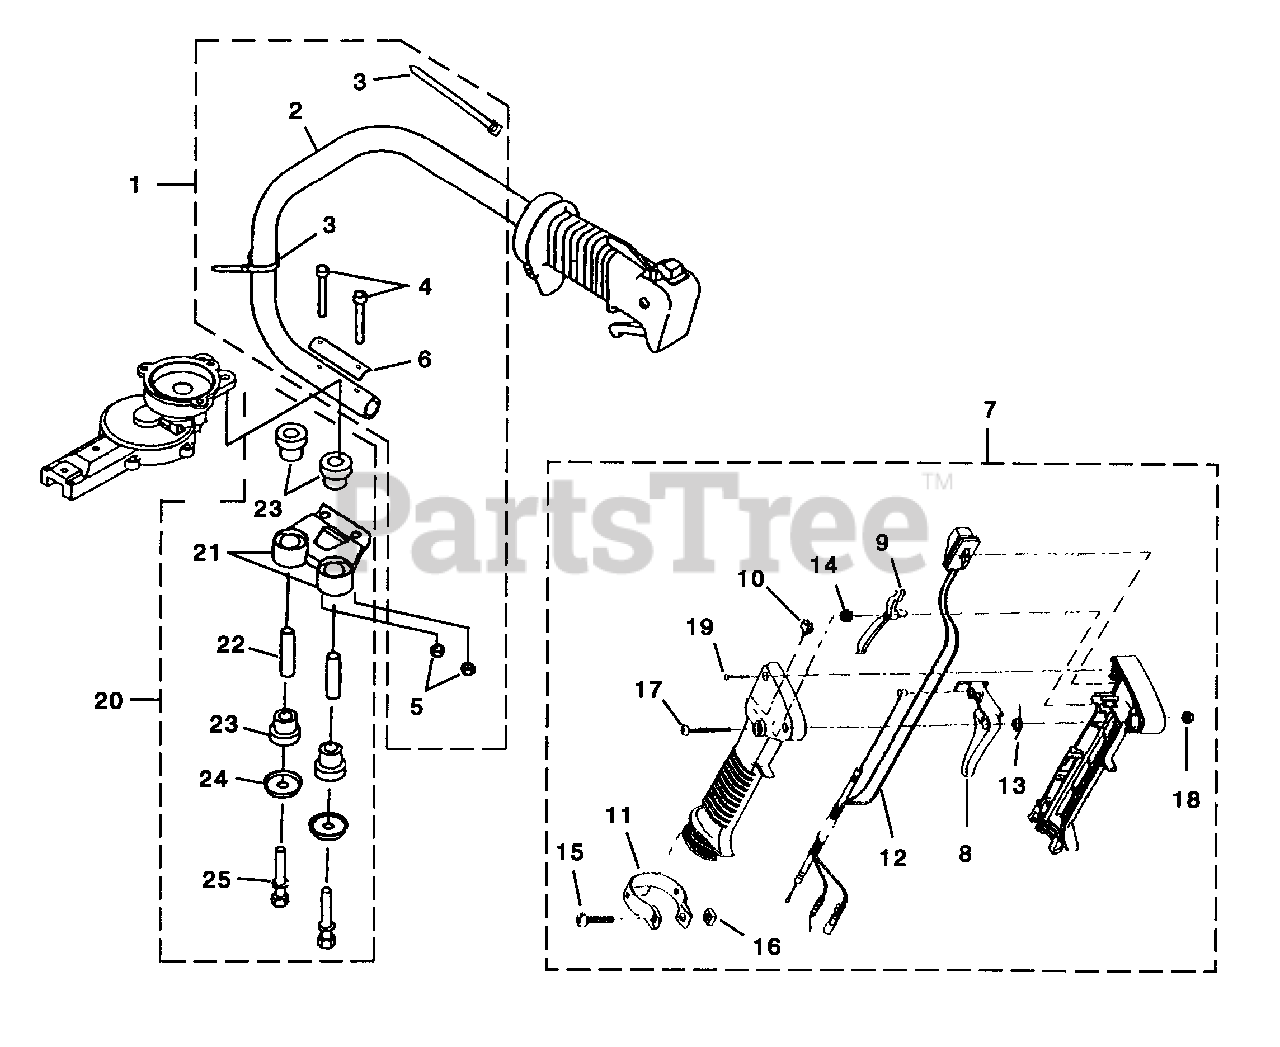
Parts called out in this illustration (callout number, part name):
1	REAR HANDLE BAR
2	HANDLE BAR-Left
3	TIE STRAPS-Grip
4	SCREW (M5 x 30)
5	NUT (M5)
6	PLATE-Handle Mounting
7	REAR HANDLE GRIP
8	TRIGGER-Throttle
9	LATCH-Throttle
10	LOCK-Throttle Start
12	THROTTLE CABLE W/ Harness
13	SPRING-Throttle Trigger
14	SPRING-Throttle Latch
19	SCREW-Self Tapping
20	ANTI VIBE KIT
21	BRACKET-Handle
22	SPACER-Collar
23	BUSHING-Anti Vibration
25	SCREW (M6 x 35 W SW)
